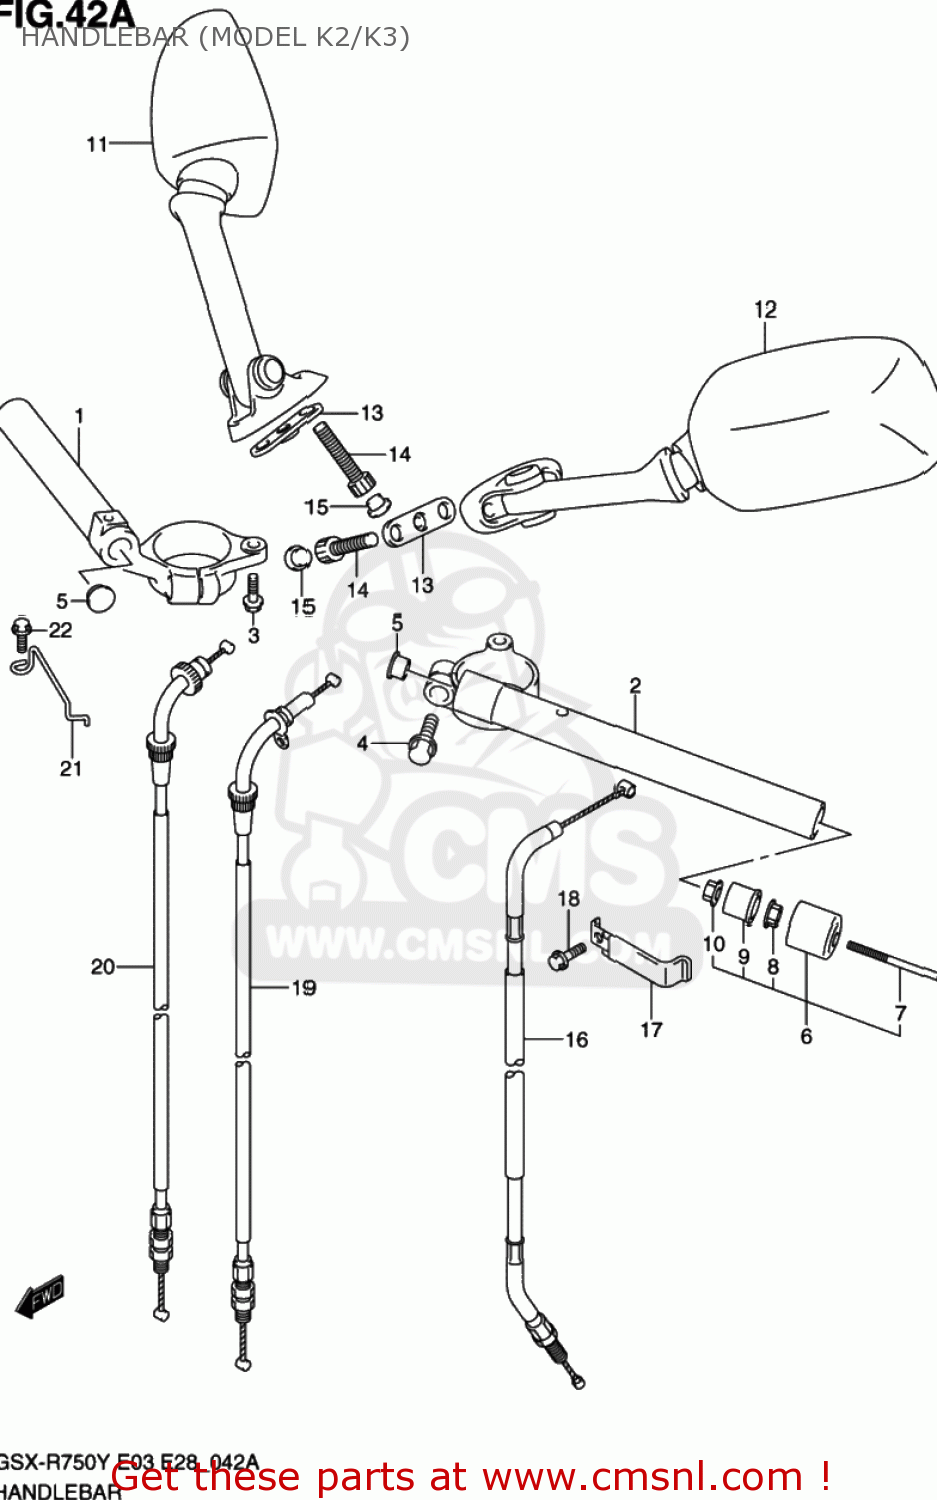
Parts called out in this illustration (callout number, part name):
1	HANDLEBAR,R
2	HANDLEBAR,L
3	BOLT
4	BOLT,HANDLEBAR
5	PLUG(OD:17)
6	BALANCER,HANDLEBAR
7	SCREW
8	NUT
9	EXPANDER,HANDLE BALANCER
10	NUT
11	MIRROR ASSY,RR VIEW,R
12	MIRROR ASSY,RR VIEW,L
13	CUSHION,RR VIEW MIRRORR
14	BOLT
15	CAP(OD:10)
16	CABLE ASSY,CLUTCH
17	CLAMP
18	BOLT
19	CABLE ASSY,THROTTLE NO.1
20	CABLE ASSY,THROTTLE NO.2
21	GUIDE, CABLE
22	BOLT
